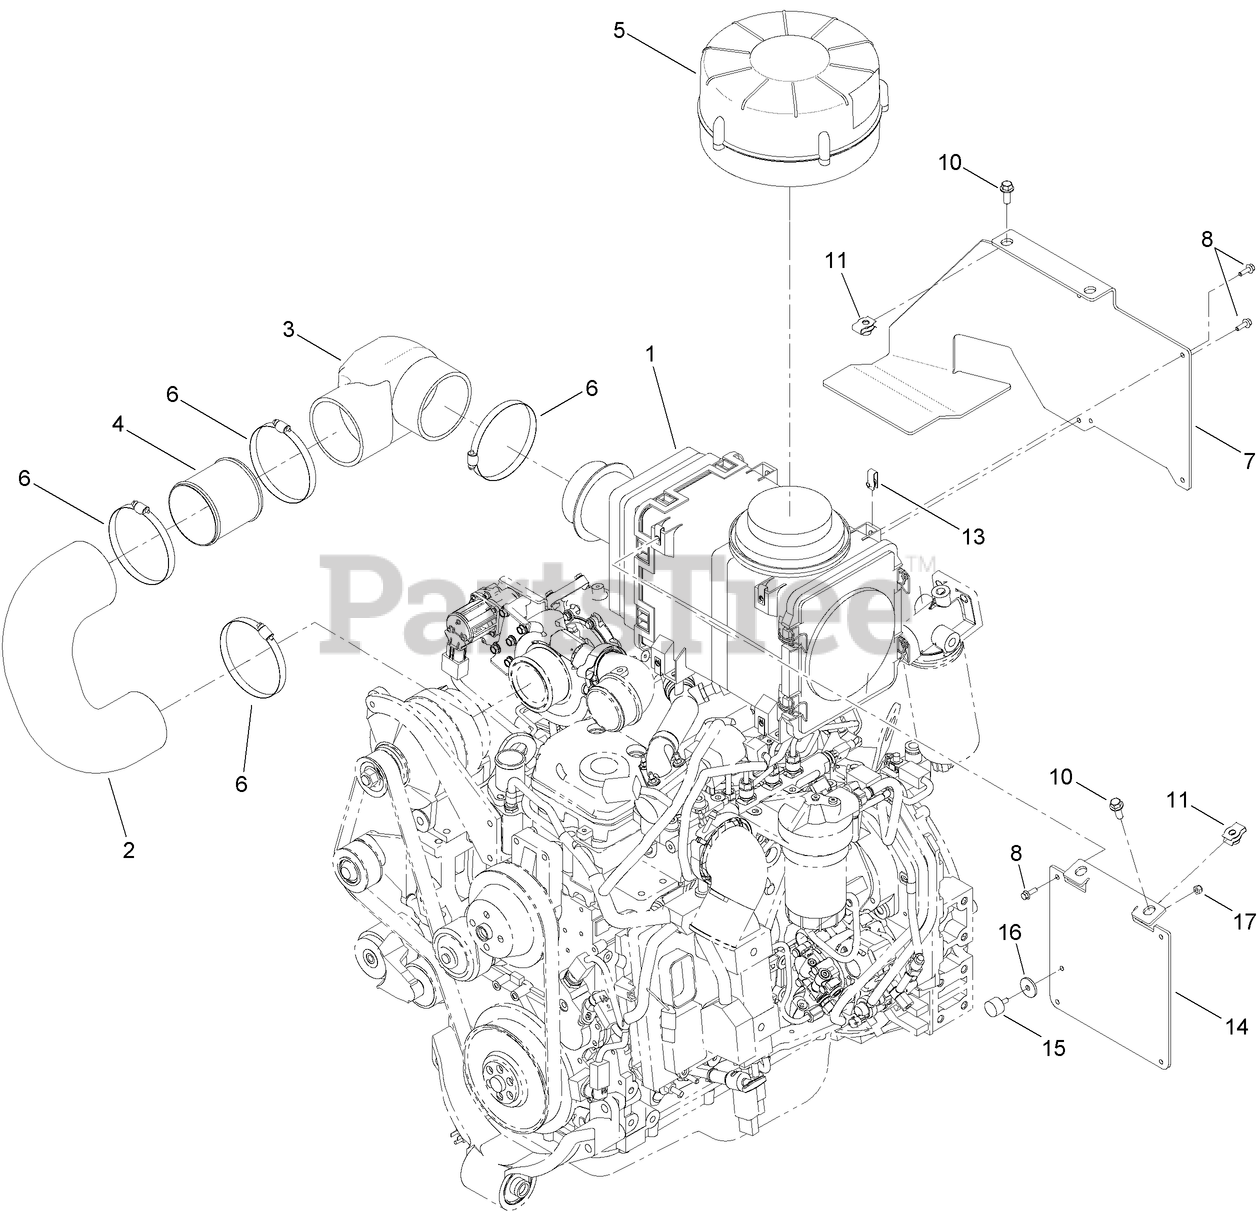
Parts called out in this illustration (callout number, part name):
1	AIR CLEANER ASM
2	HOSE-INTAKE
3	ELBOW-INTAKE, AIR CLEANER
4	CONNECTOR-INTAKE, AIR
5	PRECLEANER-INTAKE, AIR
6	CLAMP-HOSE
7	MOUNT-BOX, AIR
8	SCREW-HHF
10	SCREW-HHF
11	NUT-CLIP, U
14	BRACKET-AIR BOX
15	BUMPER-RUBBER (W/ STUD)
16	Washer-Flat
17	NUT-LOCK, NI
